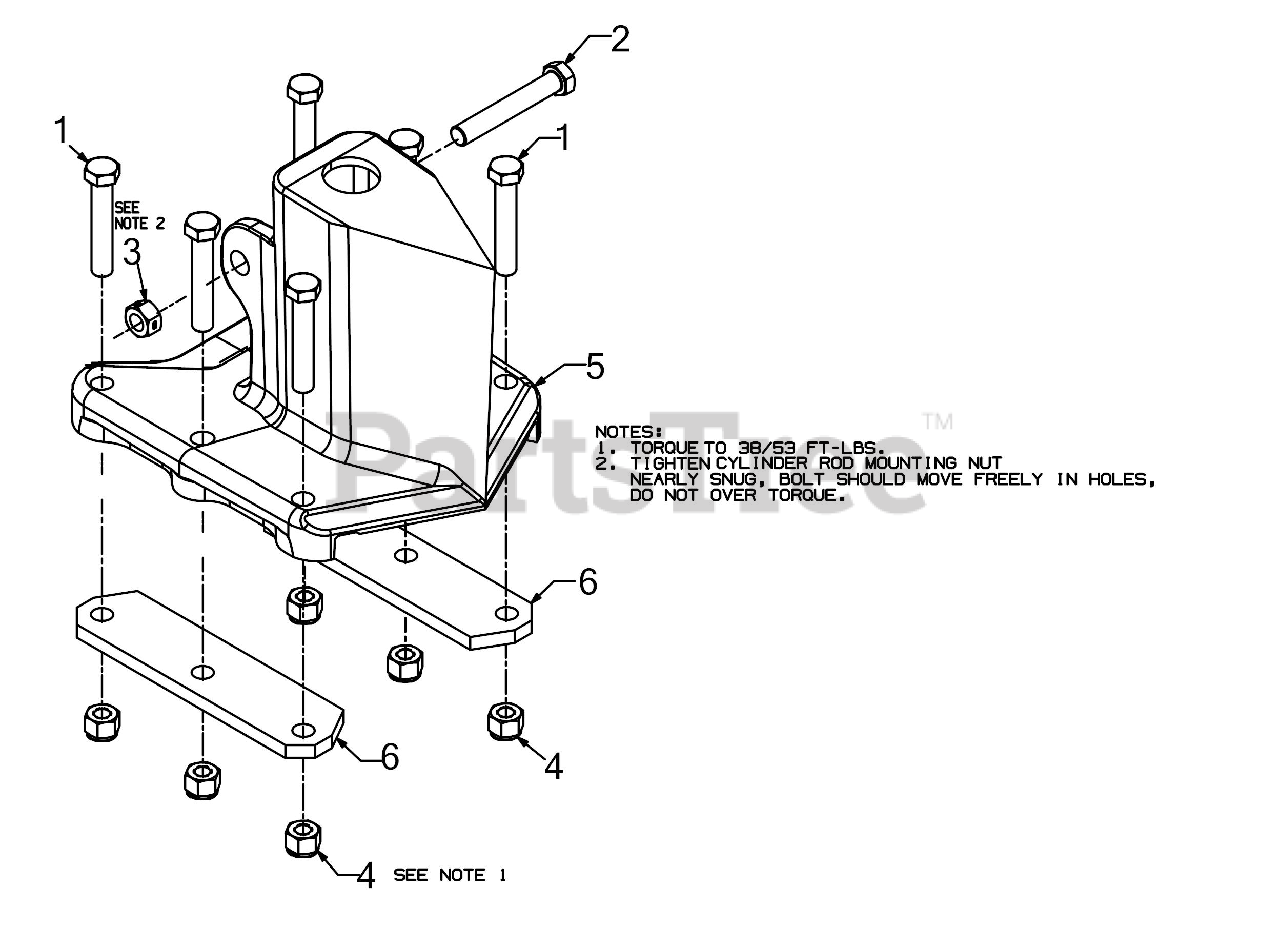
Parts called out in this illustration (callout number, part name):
1	SCREW 1/2-20 x 2.75 GR8
2	SCREW 1/2-13 x 3.25 GR5
3	HEX NUT CTR LK 1/2-13
4	HEX NUT CENTER
5	LOGSPLITTER WEDGE
